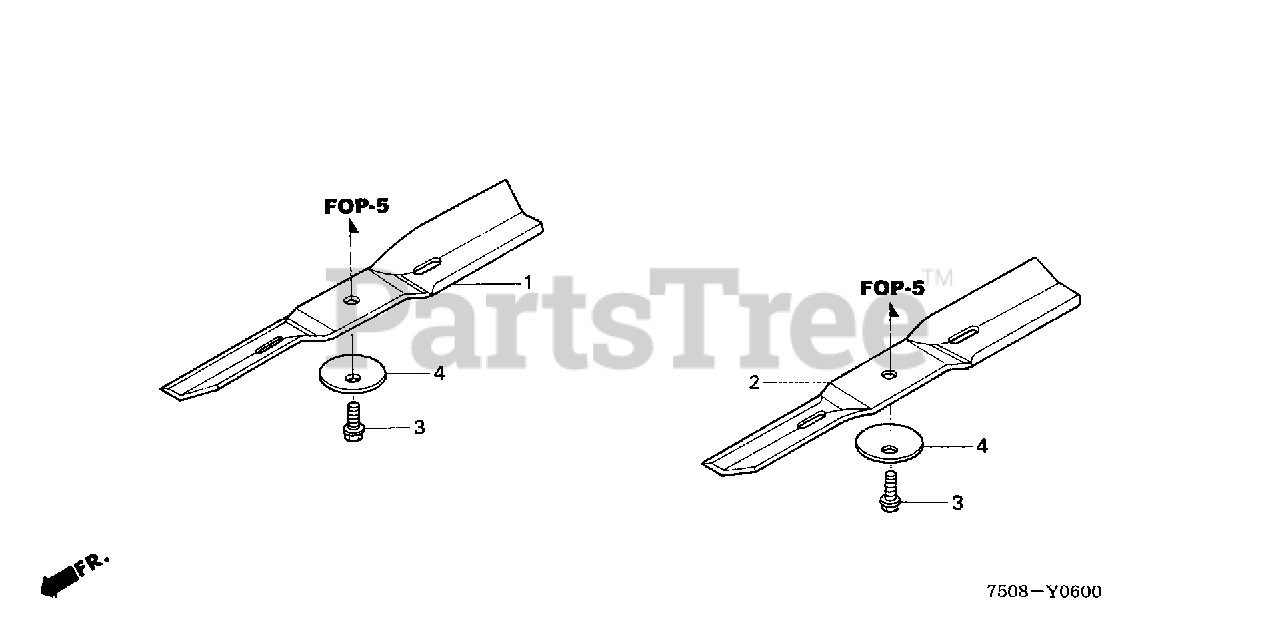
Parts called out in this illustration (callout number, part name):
1	BLADE, R. ROTARY
2	BLADE, L. ROTARY
3	BOLT, BLADE HOLDER (10X28)
4	WASHER, BLADE
